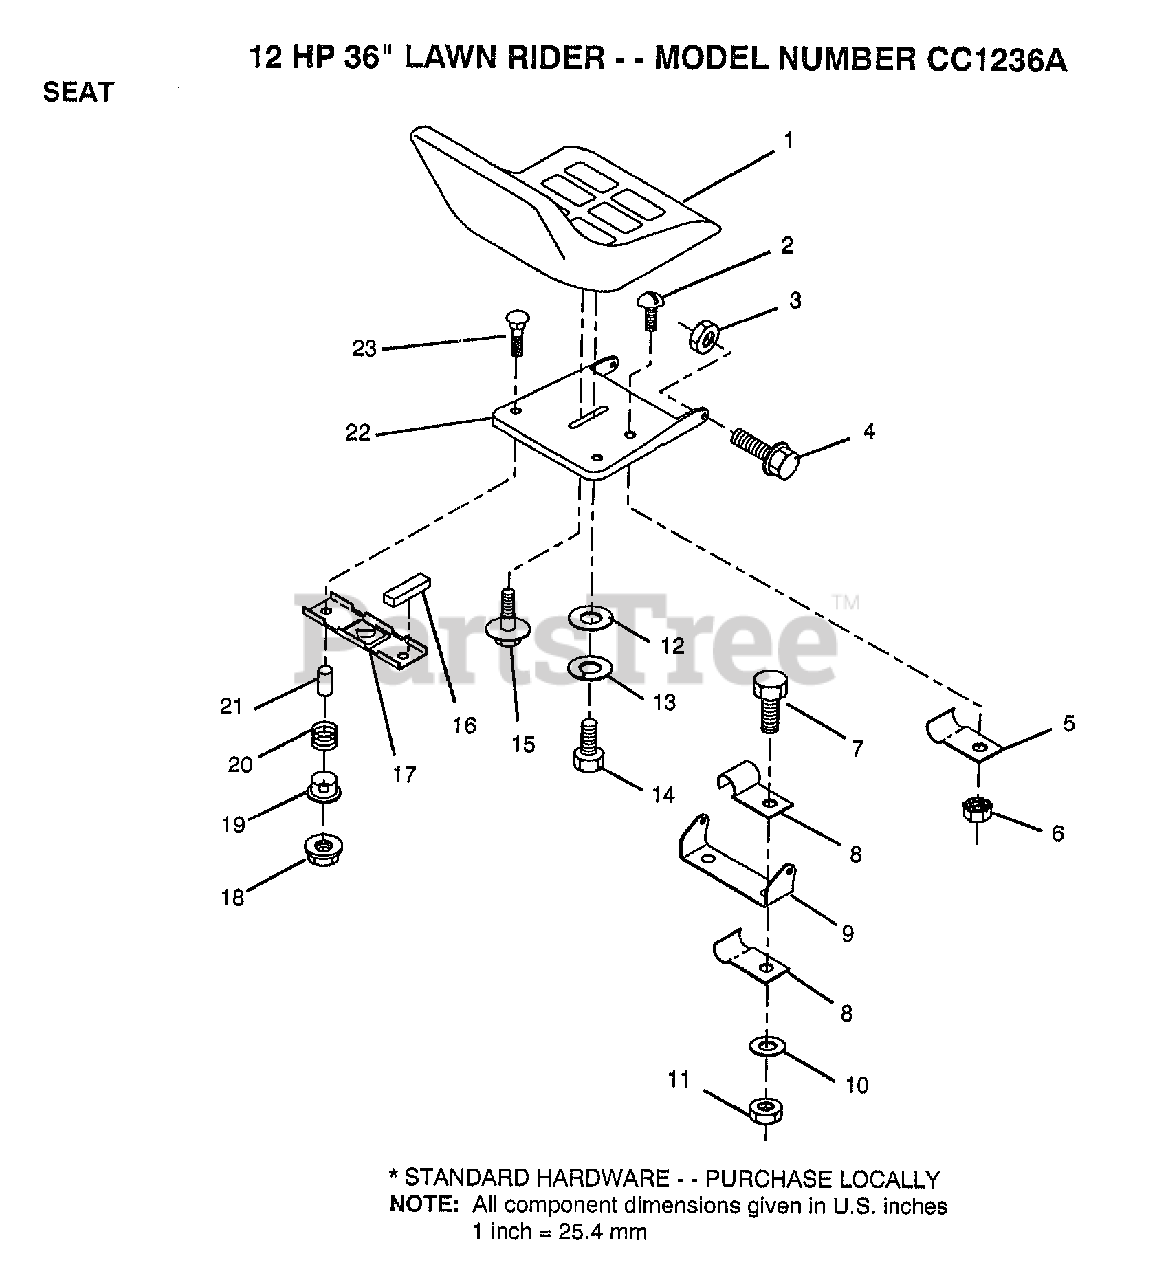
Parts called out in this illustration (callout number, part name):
6	"NUT,KEPS"
8	"CLIP,INSULATOR"
10	WASHER
12	WASHER
13	LOCKWASHER
14	BOLT
15	"BOLT,SHOULDER"
16	STRIP FORM
17	BRKT SWITCH
19	BUSHING
20	SPRING
21	SPACER SPLIT
23	BOLT
